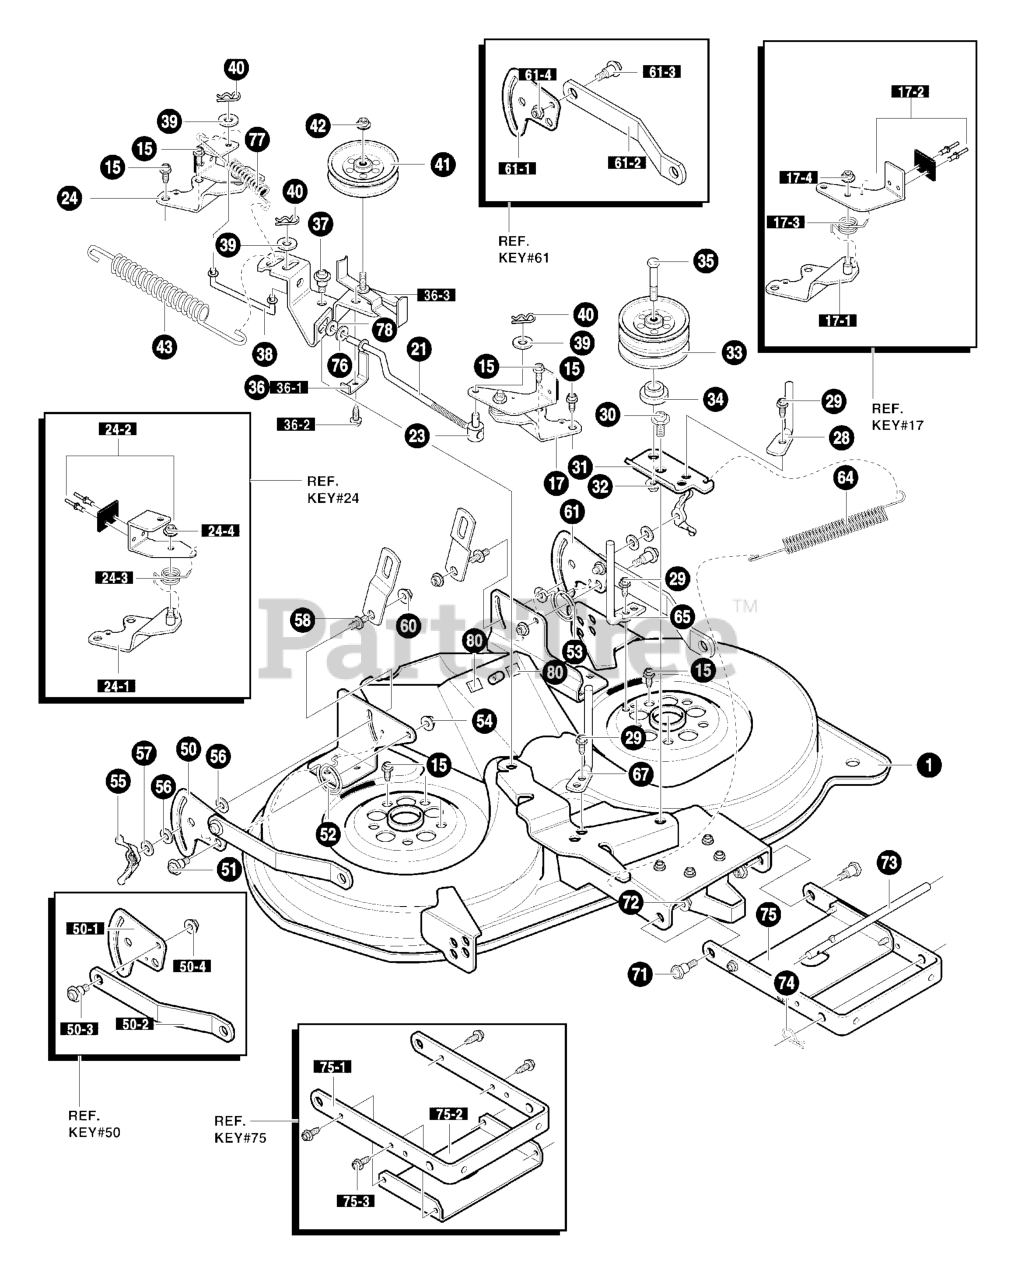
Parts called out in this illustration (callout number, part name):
1	MOWER DECK REBA
15	SCREW, 3/8-16 x 1.00
17	BRAKE ARM ASSEMBLY LH
17-1	BRAKE SUPPORT ASSEMBLY LH
17-2	BRAKE ARM ASSEMBLY LH
17-3	SPRING, TORSION
17-4	NUT, 5/16-18
21	LINK, BRAKE LH
23	NUT, ADJUSTING
24	BRAKE ARM ASSEMBLY RH
24-1	BRAKE SUPPORT ASSEMBLY RH
24-2	BRAKE ARM ASSEMBLY RH
24-3	SPRING, TORSION
24-4	NUT, 5/16-18 WDFLLK
28	BELT GUIDE
29	SCREW, 5/16-18 x 0.50
30	BOLT, .50X.75 HHSH 3/8-16
31	ARM, DOUBLE IDLER
32	NUT, 3/8-16
33	PULLEY, IDLER DOUBLE VEE
34	SPACER, DECK
35	SCREW, 3/8-16 x 3.00
36	IDLER ARM ASSY
36-1	SPRING - BELT GUIDE
36-2	SCREW 1/4-20X.50
36-3	IDLER ARM ASSEMBLY
37	BOLT, .50X.75 HHSH 3/8-16
38	LINK, BRAKE RH
39	WASHER, FLAT
40	PIN, HAIR
41	PULLEY, V IDLER 4"
42	NUT, 3/8-16
43	SPRING, EXTENSION
50	ASM. PLATE, REAR SUS. BRKT, RH
50-1	PLATE-SUSPENSION
50-2	SUSPENSION BRKT REAR
50-3	BOLT, SHOULDER 3/8-16
50-4	NUT, 3/8-16
51	BOLT, SHOULDER .375
52	SPRING, TORSION .68LG RH
53	SPRING, TORSION .68LG LH
54	NUT, 3/8-16
55	WINGNUT
56	PAD, FRICTION
57	WASHER
58	PIN, HANGER
60	NUT, 3/8-16
61	ASM. PLATE, REAR SUS. BRKT LH
61-1	PLATE - SUSPENSION
61-2	SUSPENSION BRKT REAR
61-3	BOLT, SHOULDER 3/8-16
61-4	NUT, 3/8-16
64	SPRING, EXTENSION
65	GUIDE, BELT
67	GUIDE, BELT
71	BOLT, SHOULDER .375
72	NUT, 3/8-16
73	ZINC ROD, HANGER
74	PIN, HAIR
75	SUB. ASM. BRKT & STIFFNER
75-1	BRACKET, FRONT SUSPENSION
75-2	STIFFENER, DECK
75-3	SCREW, 5/16-18 x 0.75
76	WASHER, FLAT
77	SPRING, EXTENSION 1.94LG
78	WASHER, FLAT INSULATE
80	PAD, ADHESIVE
